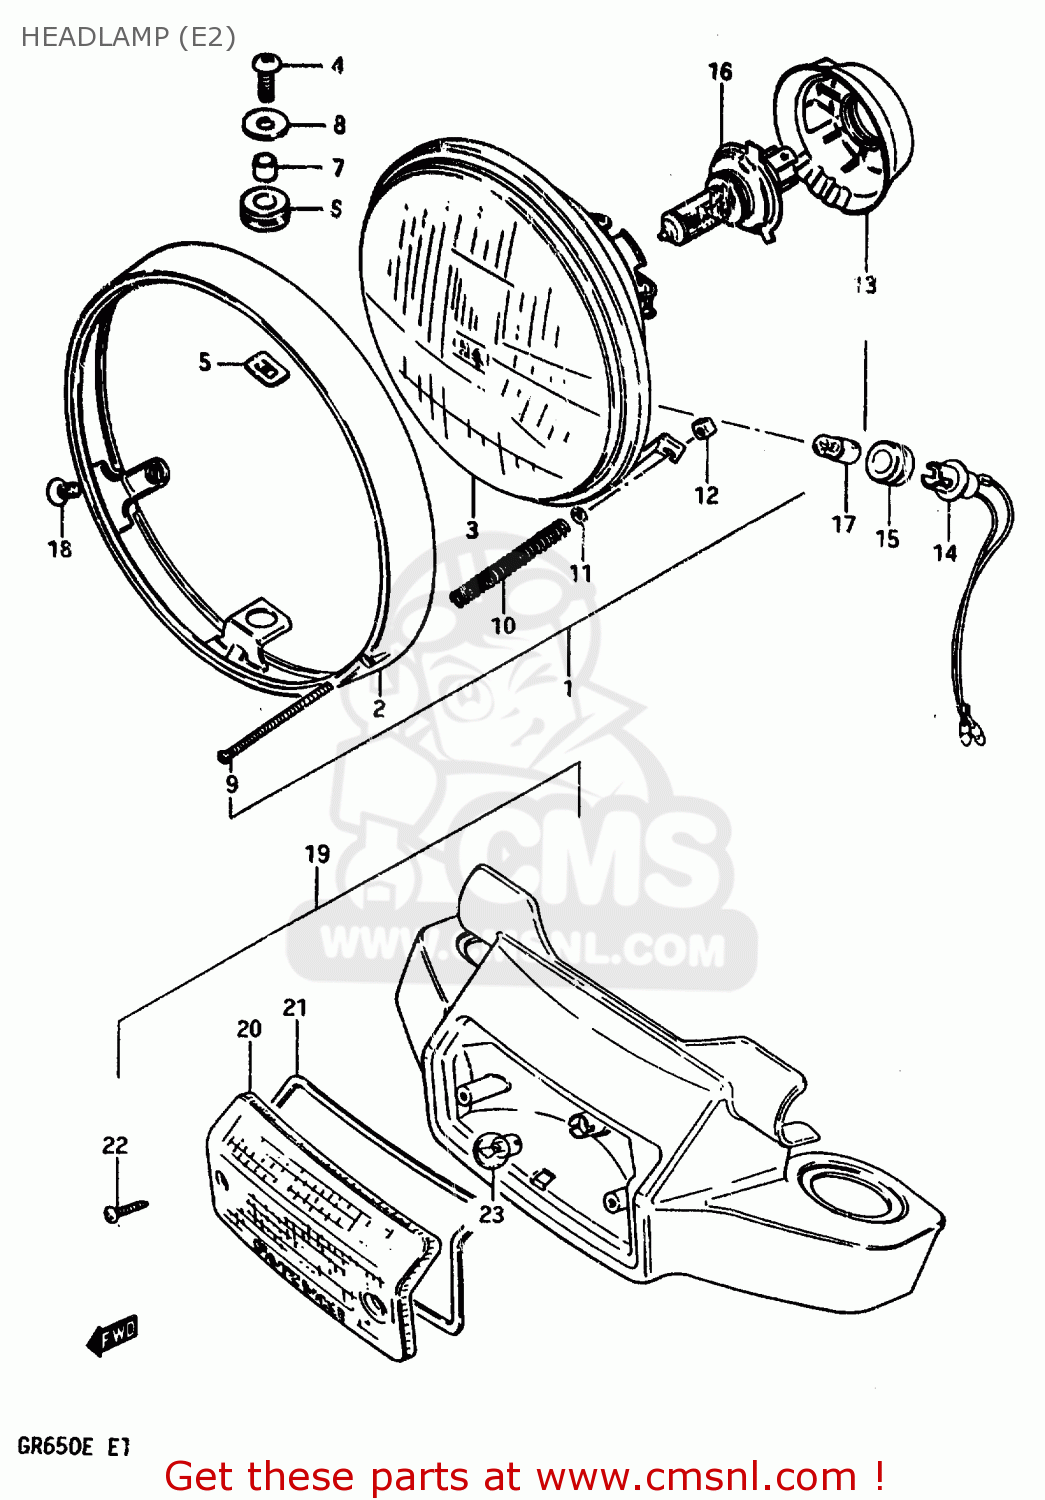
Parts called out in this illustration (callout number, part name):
1	HEADLAMP ASSY
2	RIM,HEAD LAMP
3	UNIT
4	SCREW(5X14)
5	NUT
6	CUSHION
7	SPACER
8	WASHER
9	SCREW,HEADLAMP ADJUST
10	SPRING,HEADLAMP ADJUST
11	WASHER
12	NUT
13	COVER,SOCKET
14	SOCKET
15	JOINT,RUBBER
16	BULB(12V60/55W,H4)
17	BULB(12V4W)
18	SCREW(5X12)
19	LAMP ASSY, FRONT POSITION
20	LENS
21	GASKET,POSITION LAMP
22	SCREW,POSITION LENS
23	BULB(12V4W)
